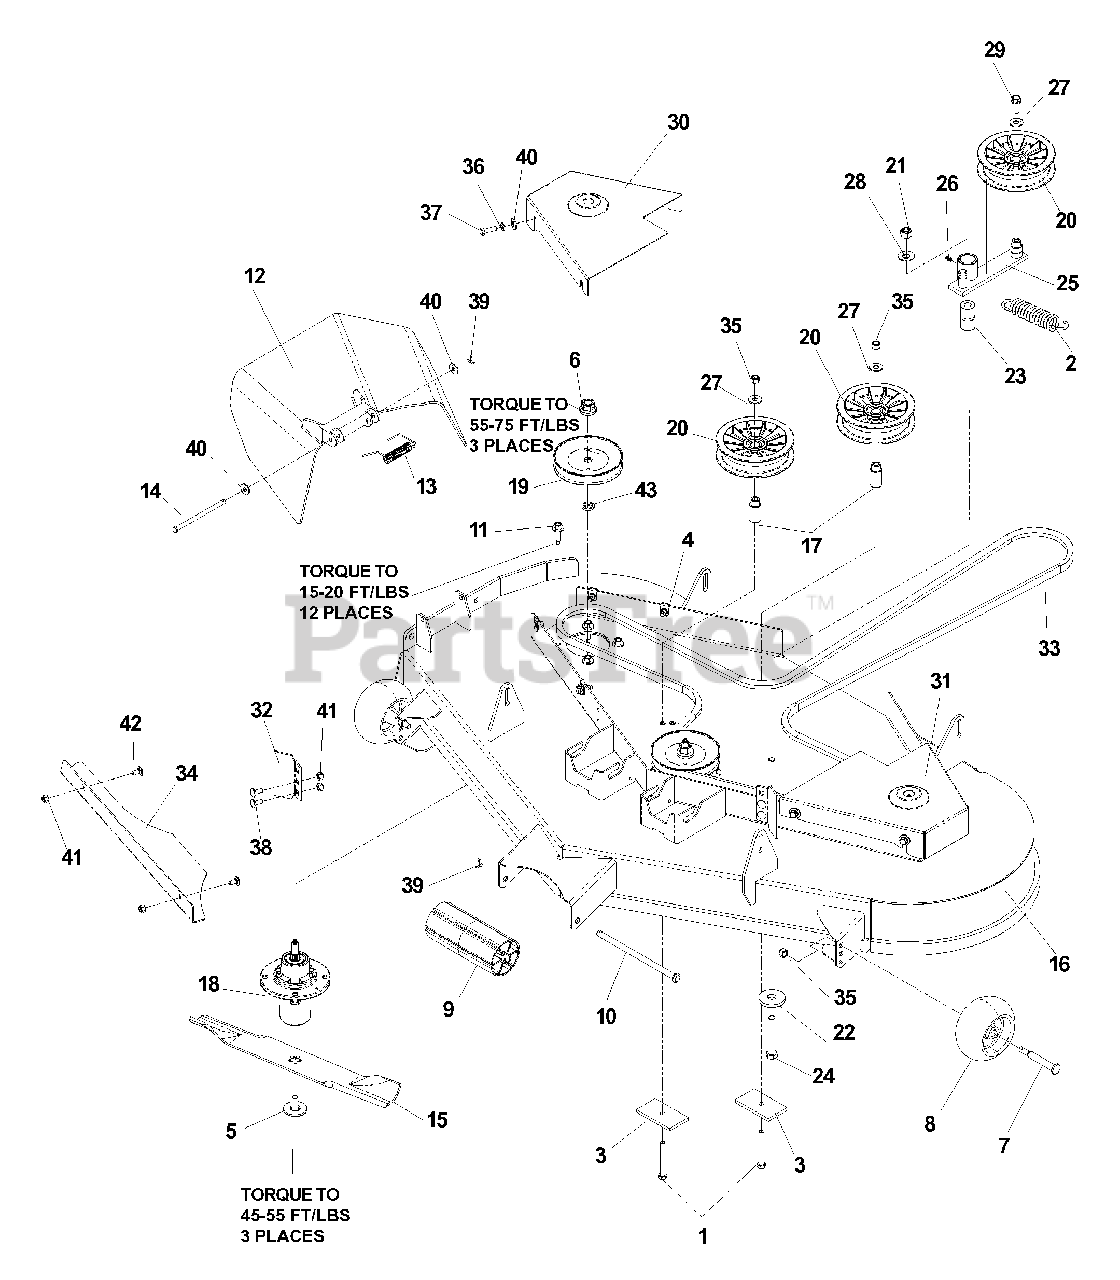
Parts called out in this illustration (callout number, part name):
1	HCS, 3/8-16, GR5
2	SPRING, EXTENSION
3	PAD
4	NUT, 5/16-18, RETAINER-U TYPE
5	BOLT, 7/16, SPEC
6	NUT, 9/16, CENTERLOCK, GR5
7	SB, 1/2 X 2 5/8, SPEC
8	WHEEL, GAUGE
9	ROLLER, NOSE
10	ROD, TOLLER, NOSE, NARROW
11	SCREW, 5/16-18 X 1 3/8, WASH HD, SPEC
12	DISCHARGE CHUTE
13	SPRING, TORSION
14	PIN-CLEVIS, 5/16 DIA X 5.19
15	BLADE, 18"
16	DECK W/DECALS
17	IDLER BUSHING
19	PULLEY
20	IDLER PULLEY, NYLON
21	NUT, 1/2-13, NYLOC
22	WASHER, .65 X 2 X .25, SUPPORT
23	BUSHING-PIVOT
24	HCS, 1/2-13 X 3 1/4, GR5
26	ZERK, STRAIGHT, 1/4-28
27	WASHER, 3/8
28	WASHER, .562 X 1.38 X 14
29	HCS, 3/8-16 X 1, GR5, WHIZLK
30	BELT SHIELD, RIGHT
31	BELT SHIELD, LEFT
34	CONFINEMENT PLATE
35	NUT, 3/8-16, NYLOC
36	WASHER, 5/16
37	HCS, 5/16-18 X 1, GR5
38	RHSNB, 5/16-18 X 3/4, GR5
39	PIN COTTER, 1/8 X 3/4
40	WASHER, 5/16
41	NUT, 5/16-18, NYLOC
42	RHSNB, 5/16-18 X 5/8, GR5
43	WASHER, .675, SPACER
